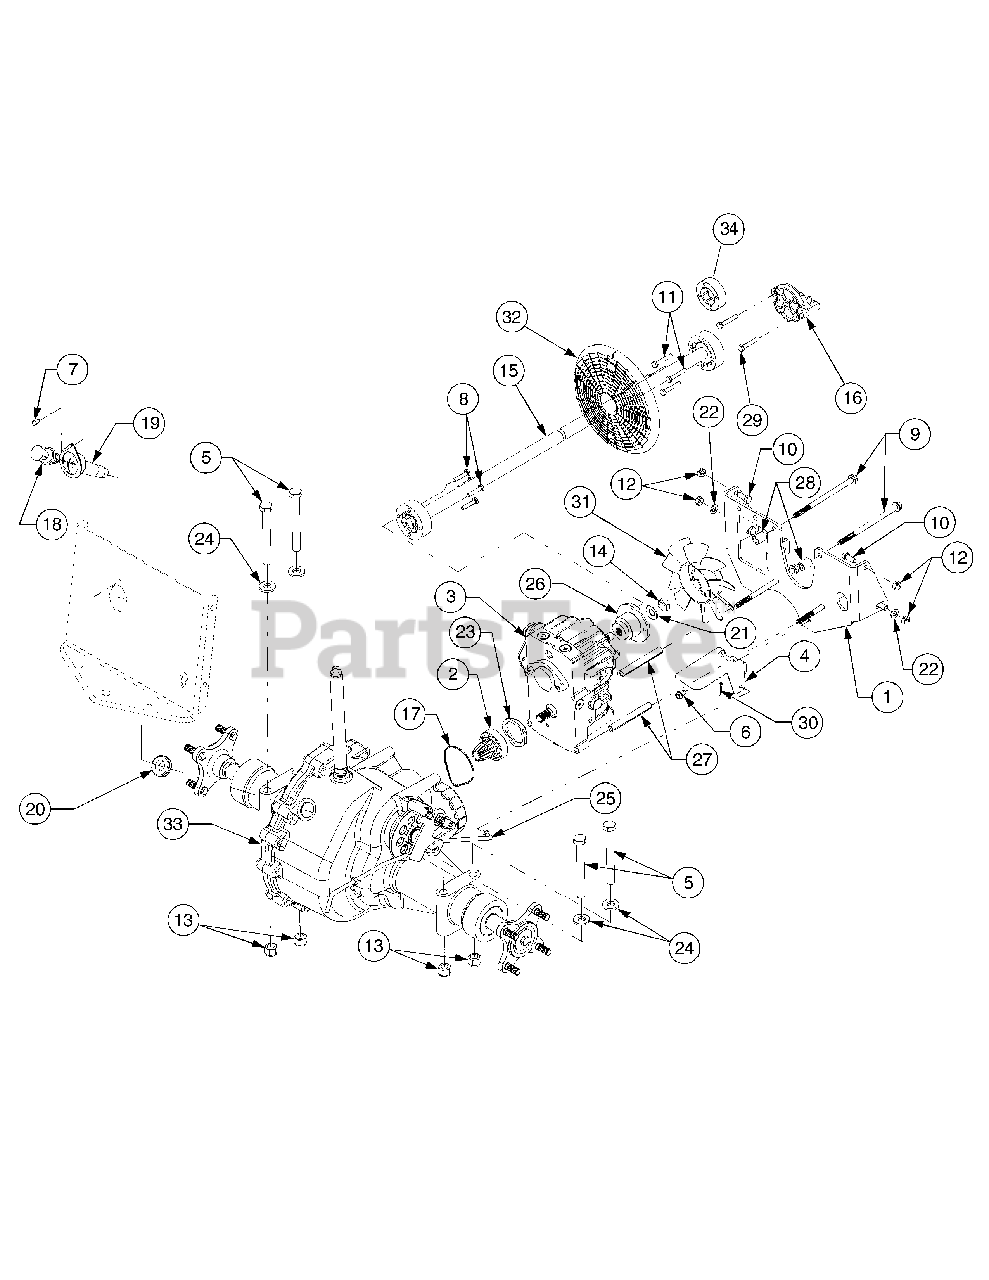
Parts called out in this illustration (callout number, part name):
1	Bracket, Torque
2	Gear Assembly, Pinion
3	Pump, Hydrostatic
5	Screw, Hex Cap, 1/2-20 x 4.5 GR5
6	Scrw, Hx Wsh Hd Tapp, 1/4-20 x .5
7	Scrw, Hx Wsh Hd Tapp, 10-16 x .44
8	Screw, Hex Patch, 1/4-20 x 1.25 GR5
9	Scrw, Hx Hd Tapp, 5/16-18 x 5.25
10	Screw, Hex Cap, 5/16-18 x .75 GR5
11	Screw, Hex Patch, 1/4-20 x 1.62 GR5
12	Nut, Hex Cntr Lock, 5/16-18
13	Nut, Hex Nylon Lock, 1/2-20 GR2
14	Nut, Hex Top Lock Jam, 1/2-20
15	Shaft, Drive, 30.625 Lg
15	Shaft, Drive, 29.75 Lg
16	Adapter, Engine
17	Seal, Gland
18	Dipstick, Transmission
19	Holder, Dipstick
20	Grommet, Rubber, .75 x 1.063
21	Washer, Belleville
22	Washer, Flat, .344 x .688 x .065
23	Washer, Spring
24	Washer, Flat, .531 x 1.062 x .134
25	Rod, Hydro Dump Valve
26	Adapter, Hydro Pump
27	Spacer, Hydro, .323 x .443 3.51
28	Spacer, Hydro, .323 x .600 x .74
29	Screw, Hex Patch, M10-1.5x 90mm
30	Internal Cotter Pin
31	Fan, Pump
32	Screen, Engine
33	Transmission, Hydro
34	Adapter, Drive Shaft
